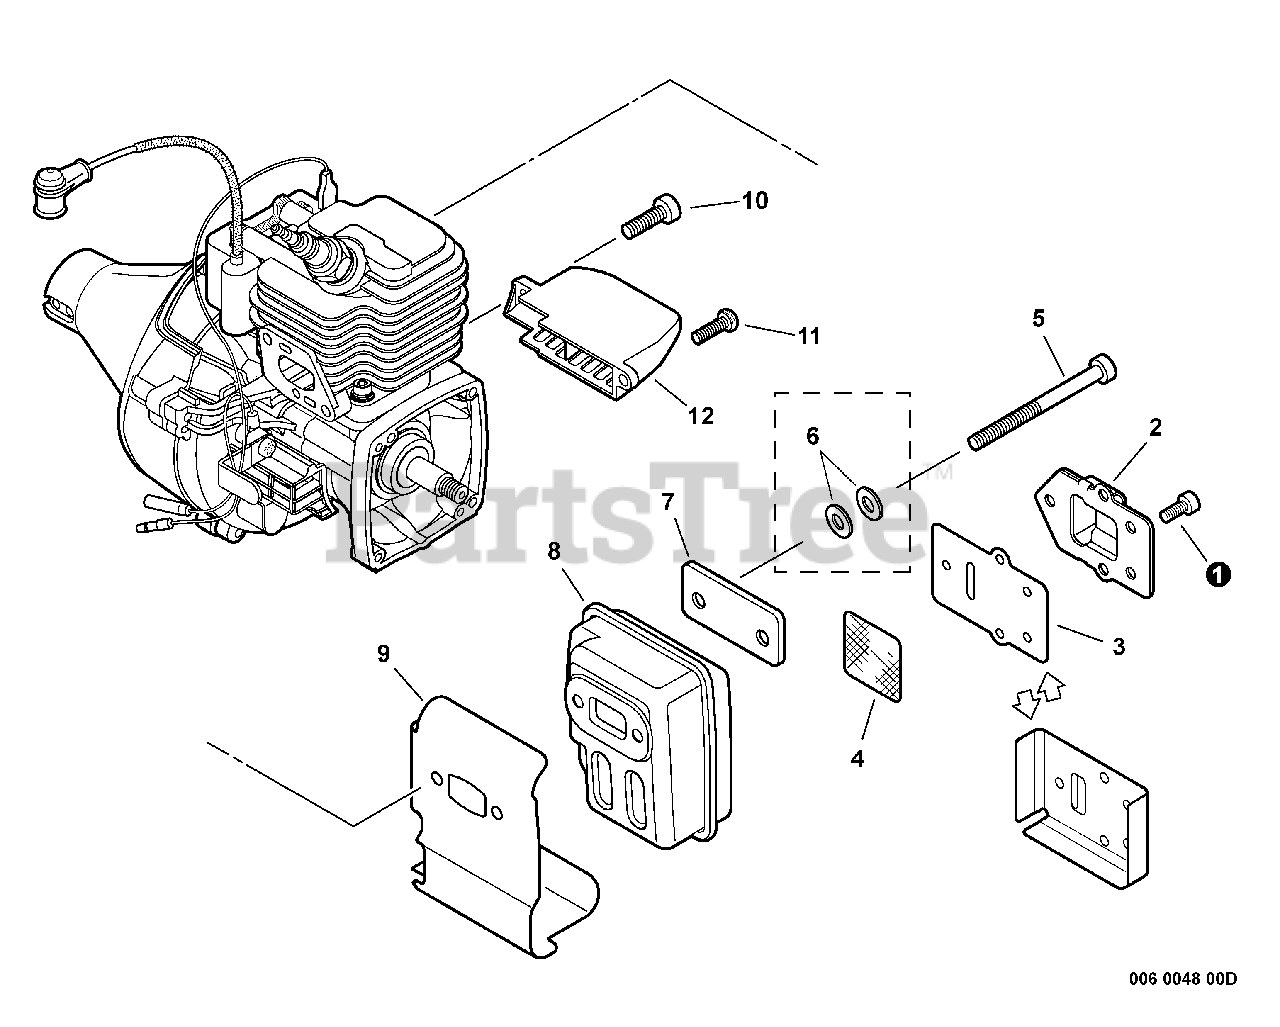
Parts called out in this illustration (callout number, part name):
1	SCREW - 4X8
2	GUIDE, EXHAUST
3	GASKET, EXHAUST
4	SCREEN, SPARK ARRESTOR
5	SCREW - 5X55
6	WASHER - CONICAL
8	MUFFLER
9	SHIELD, EXHAUST
10	SCREW - 5X16
11	SCREW - 5X16
12	DUCT, AIR
